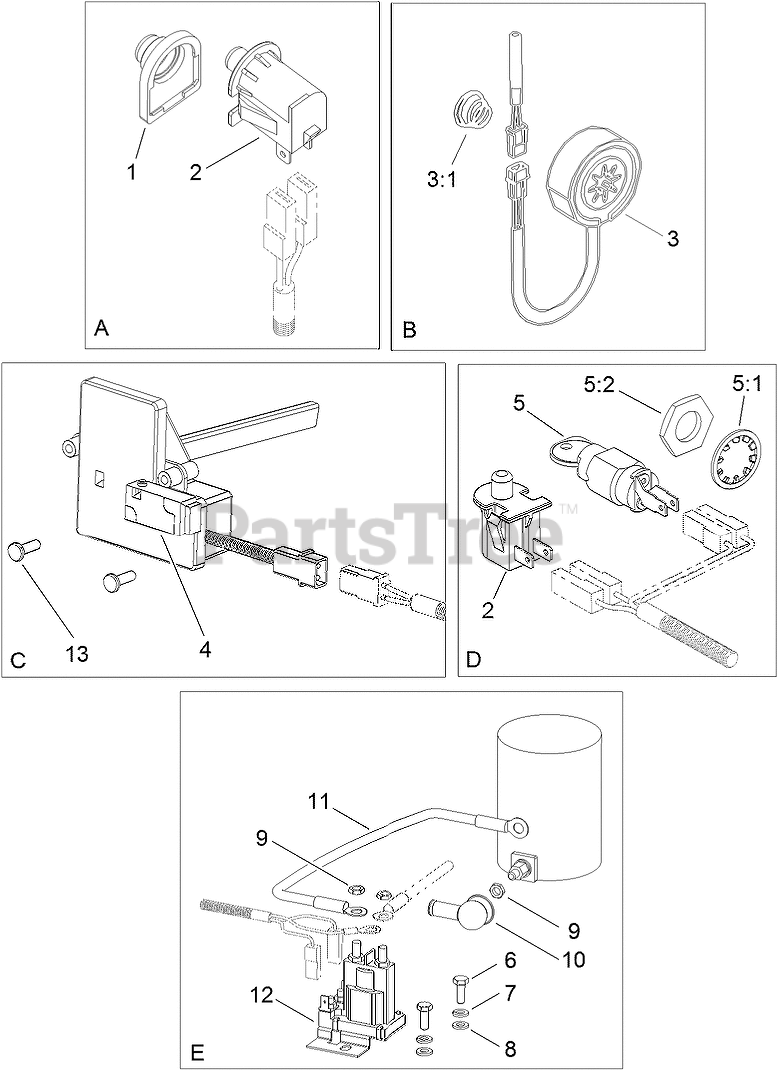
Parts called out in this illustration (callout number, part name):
1	COVER-PROTECTIVE
2	SWITCH-DELTA
3	MAGNET ASM
3:1	SPRING-COMPRESSION
4	SWITCH-OMRON
5	STARTER SWITCH ASM
5:1	WASHER-TOOTH, INTERNAL
5:2	NUT-HH
6	SCREW-HH
7	WASHER-SPRING
8	WASHER-FLAT
9	NUT-HHF
10	BOOT-RUBBER
11	LEAD-STARTER, ELECTRIC
12	Solenoid
13	Screw
